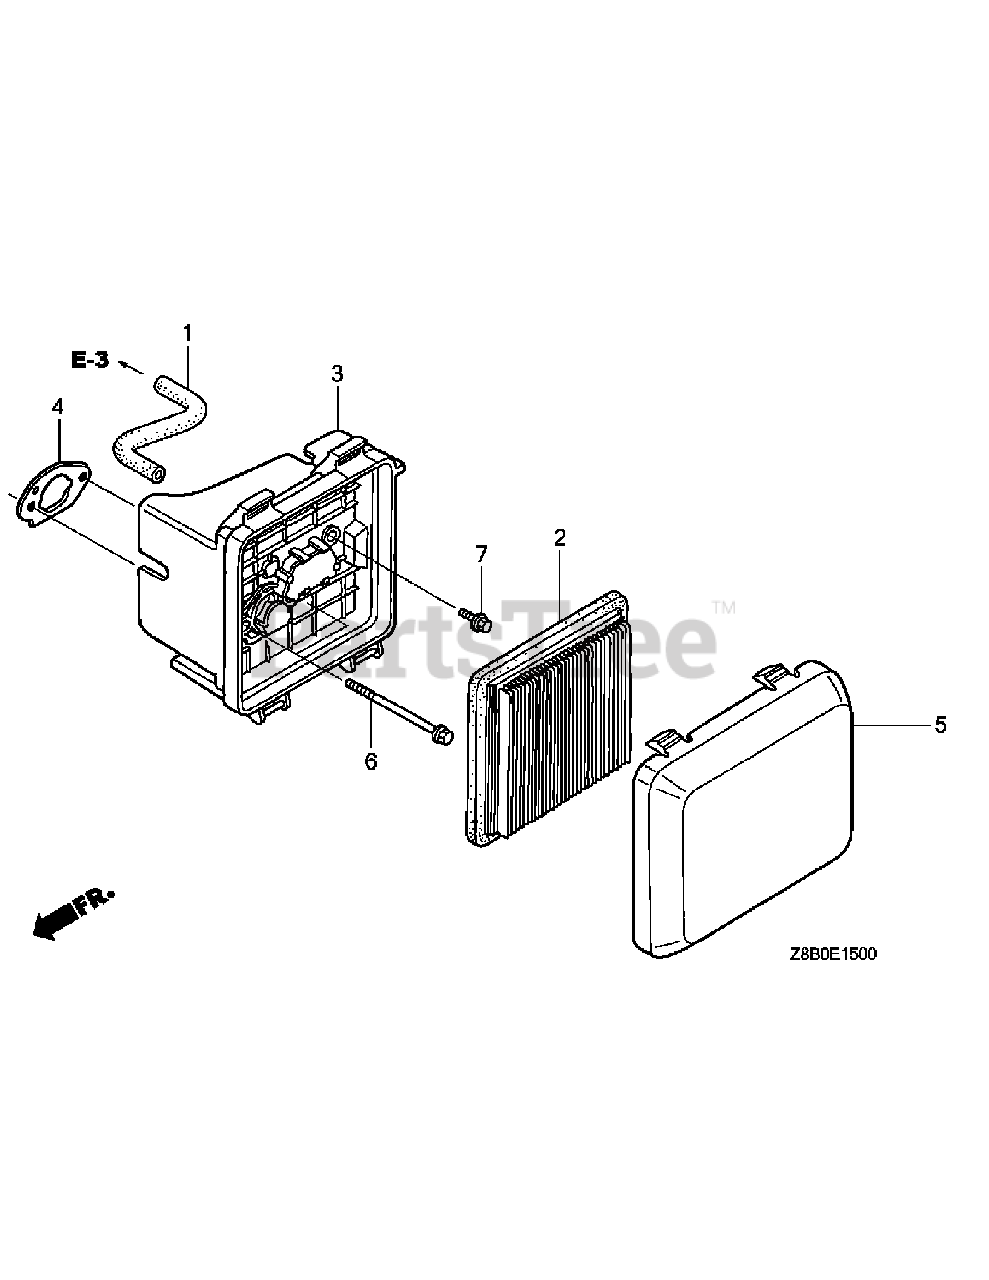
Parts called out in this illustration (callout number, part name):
1	TUBE, BREATHER
2	PRI; ELEMENT, AIR CLEANER
3	CASE ASSY., AIR CLEANER
4	GASKET, AIR CLEANER
5	PRI; COVER, AIR CLEANER
6	BOLT, FLANGE (6X86) (CT200)
7	BOLT, FLANGE (6X14)
